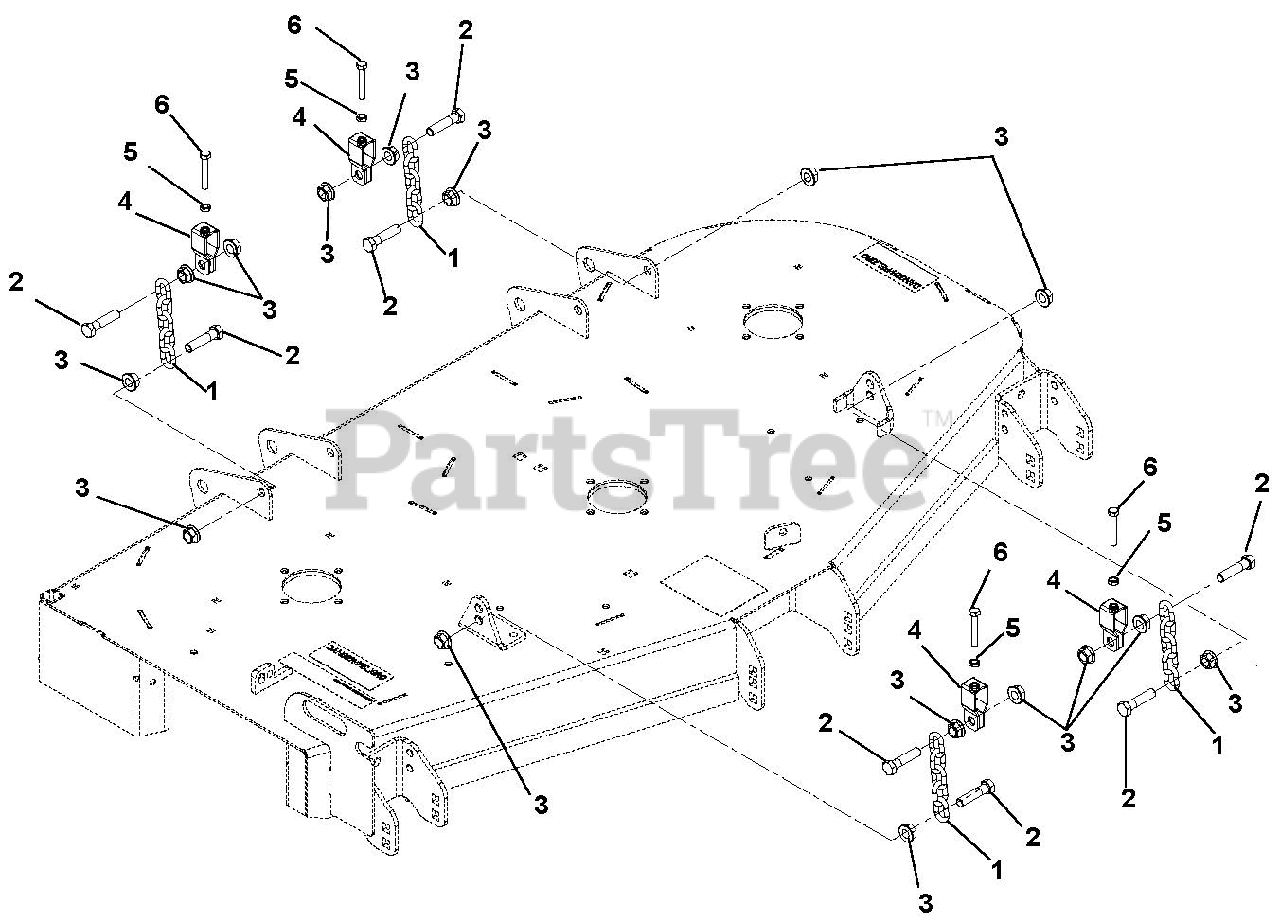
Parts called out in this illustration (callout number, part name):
1	Chain, Link
2	Bolt, Hex M12-1.75 x 50 Class 8.8
3	Nut, Spin Lock, Flange M12-1.75
4	Bracket, Deck Leveling
5	Nut, Jam .312-18
6	Bolt, Hex .312-18 x 2.00 FTH Grade 5
